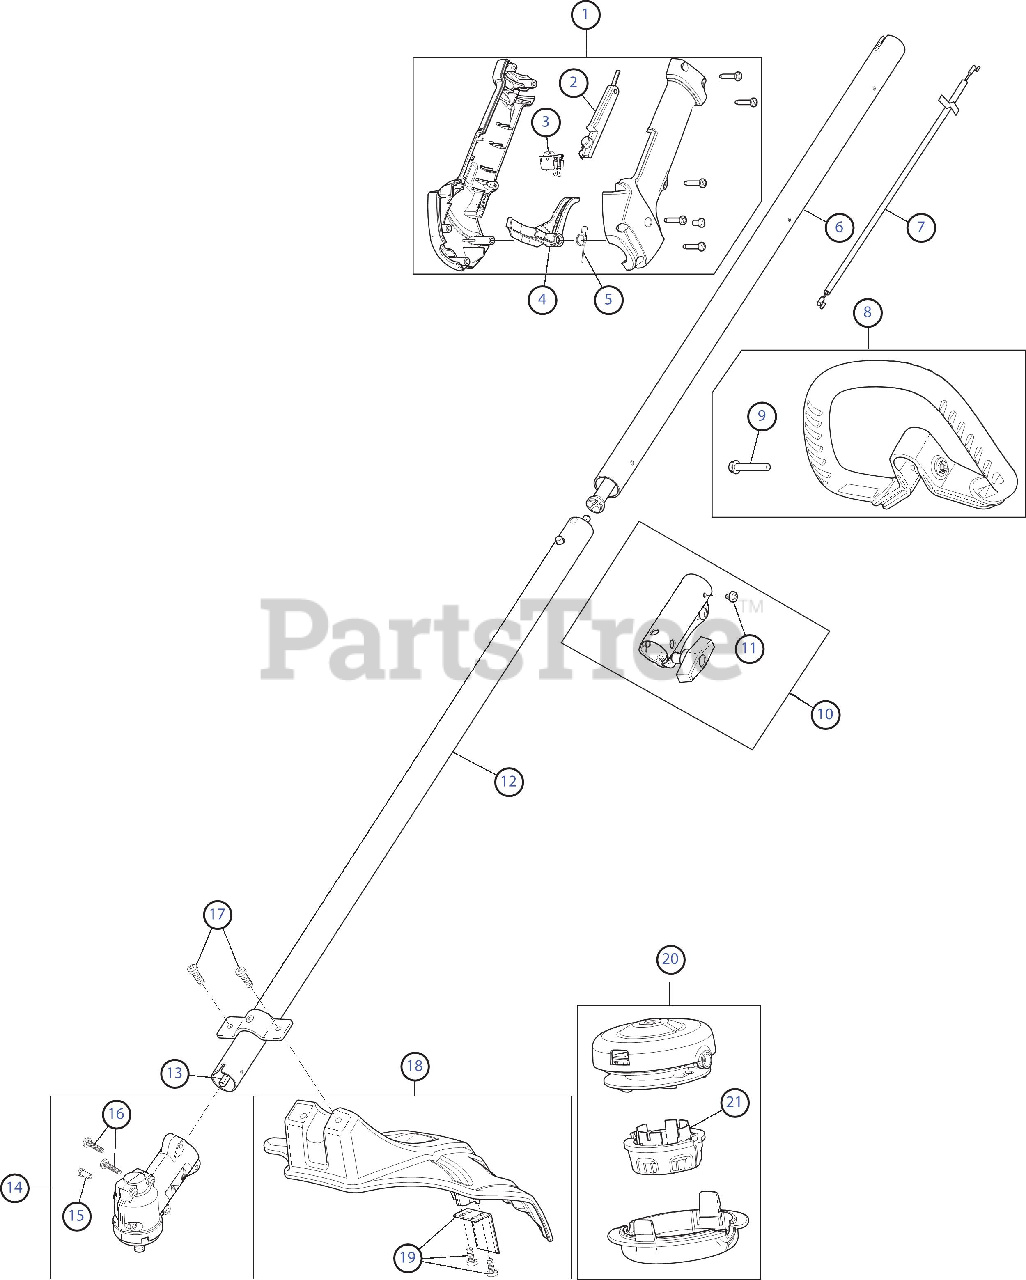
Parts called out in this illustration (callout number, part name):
1	Throttle Housing Assembly (Incl. 2 - 5)
2	Throttle Trigger Lock-Out
3	Throttle Switch Assembly
4	Throttle Trigger
5	Throttle Trigger Spring
6	Upper Drive Shaft Assembly
7	Throttle Cable
8	D-Handle Assembly (Incl. 9)
10	Split Boom Coupler (Incl. 11)
11	Coupler Anti-Rotation Screw
12	Lower Drive Shaft Housing
13	Lower Flexible Drive Shaft
14	Gearbox Assembly (Incl. 15 and 16)
15	Anti-Rotation Screw
16	Gearbox Mounting Hardware
17	Shield Mounting Screws
18	Shield Assembly (Incl. 19)
19	Blade Assembly
20	Cutting Head Assembly (Incl. 20)
